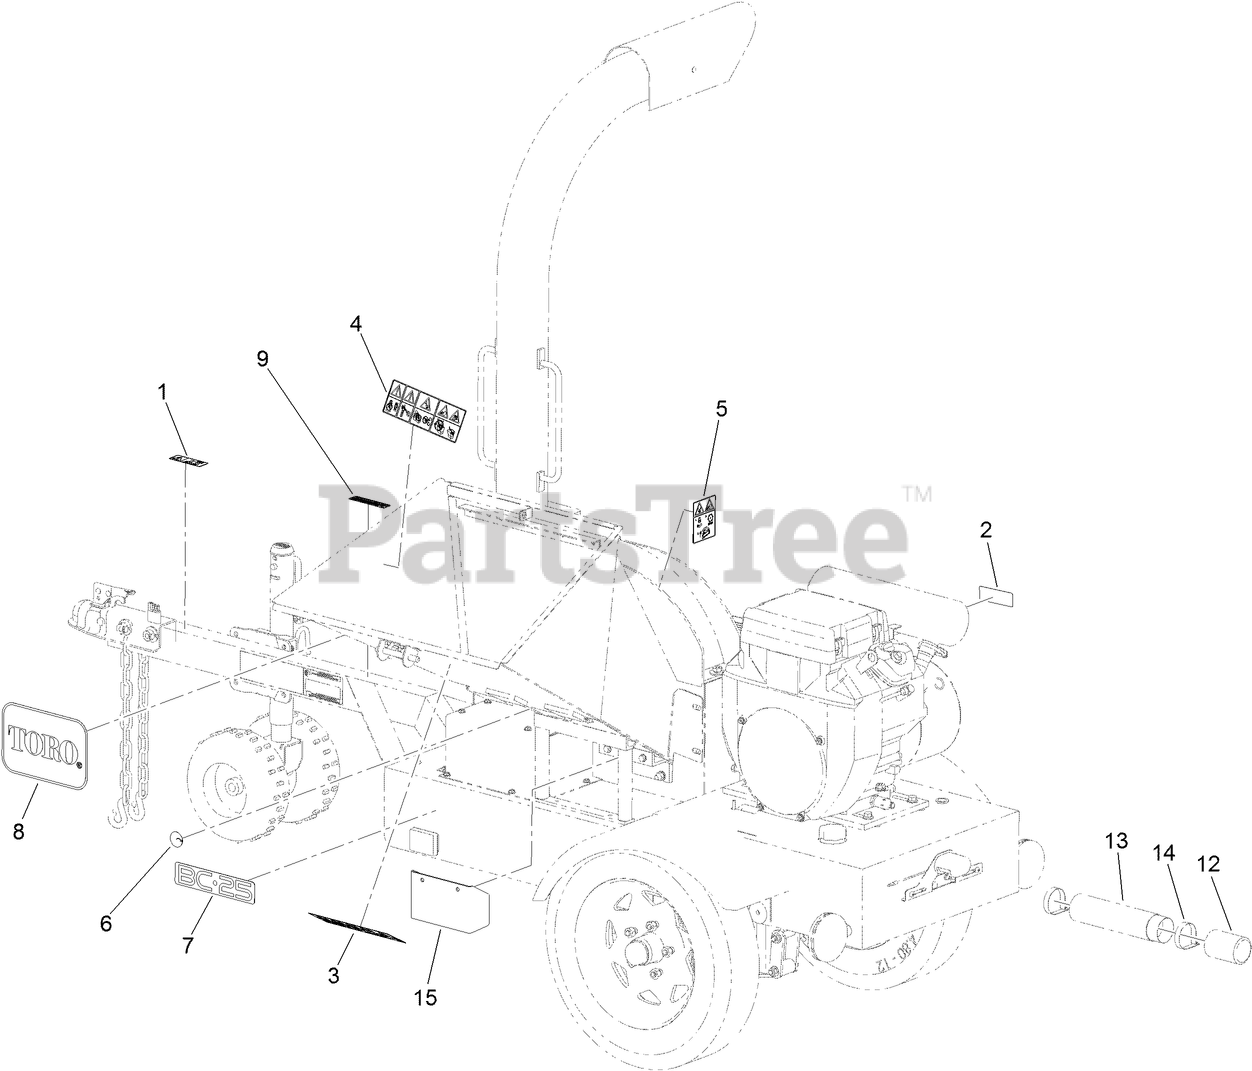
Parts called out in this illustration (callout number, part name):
1	DECAL-CAUTION
2	DECAL-WARNING, SHIELDS
3	DECAL-DANGER
4	DECAL-DANGER
5	DECAL-DANGER
6	DECAL-INDICATOR, ROTATION
8	DECAL
9	DECAL-ARRESTER, SPARK
12	CAP-HOUSING
13	TUBE-MANUAL
14	CLAMP-R
15	BRACKET-COVER, BLADE
